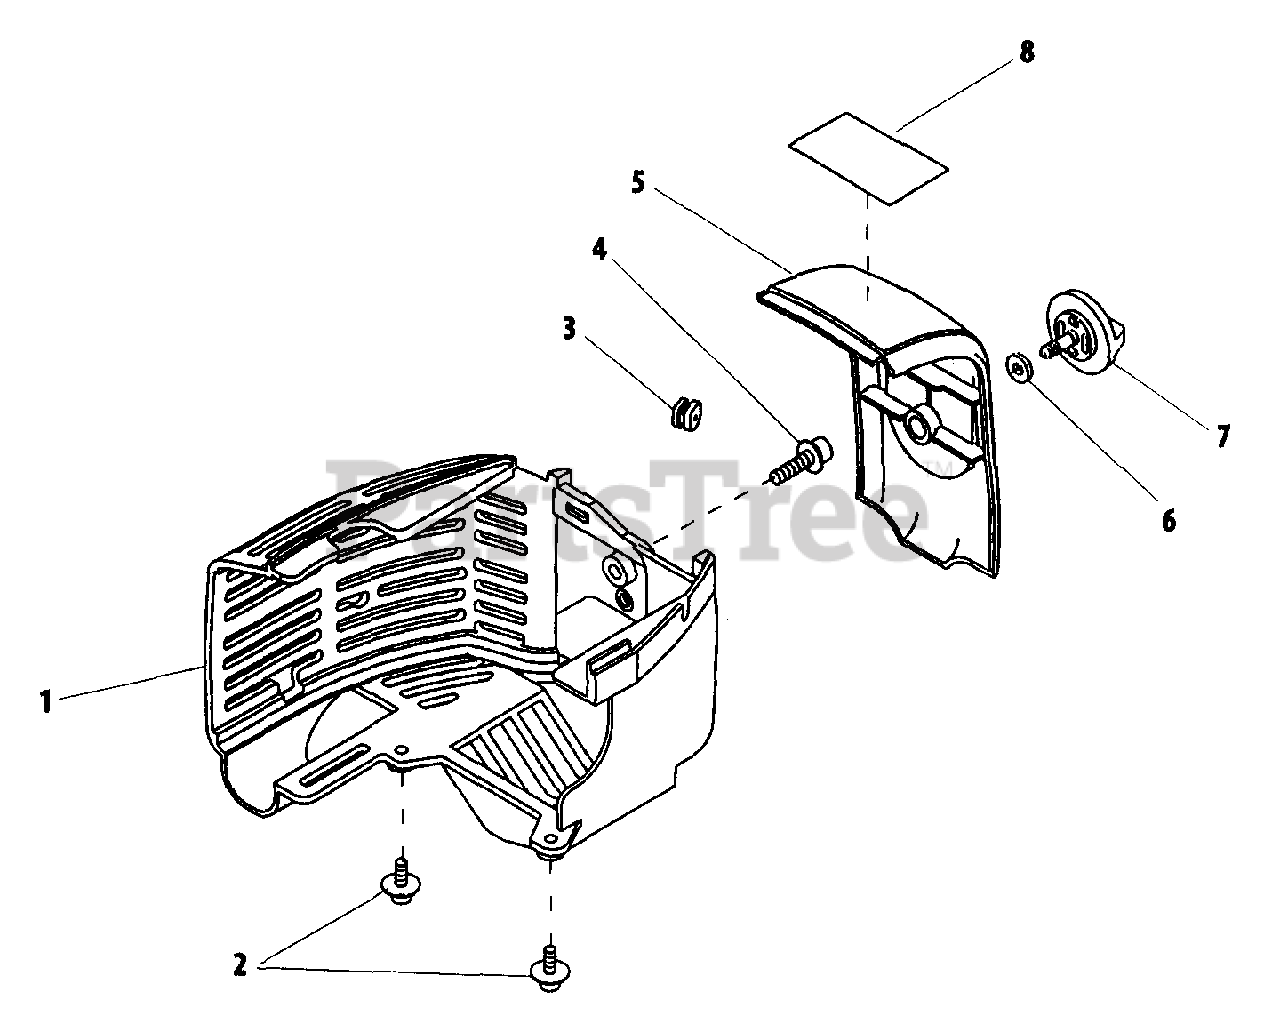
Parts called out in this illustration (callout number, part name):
1	COVER, ENGINE
2	SCREW - 4X12
3	GROMMET
4	SCREW - 5X20
5	COVER
6	WASHER - VINYL
7	THUMBSCREW
8	LABEL, MODEL HT230
